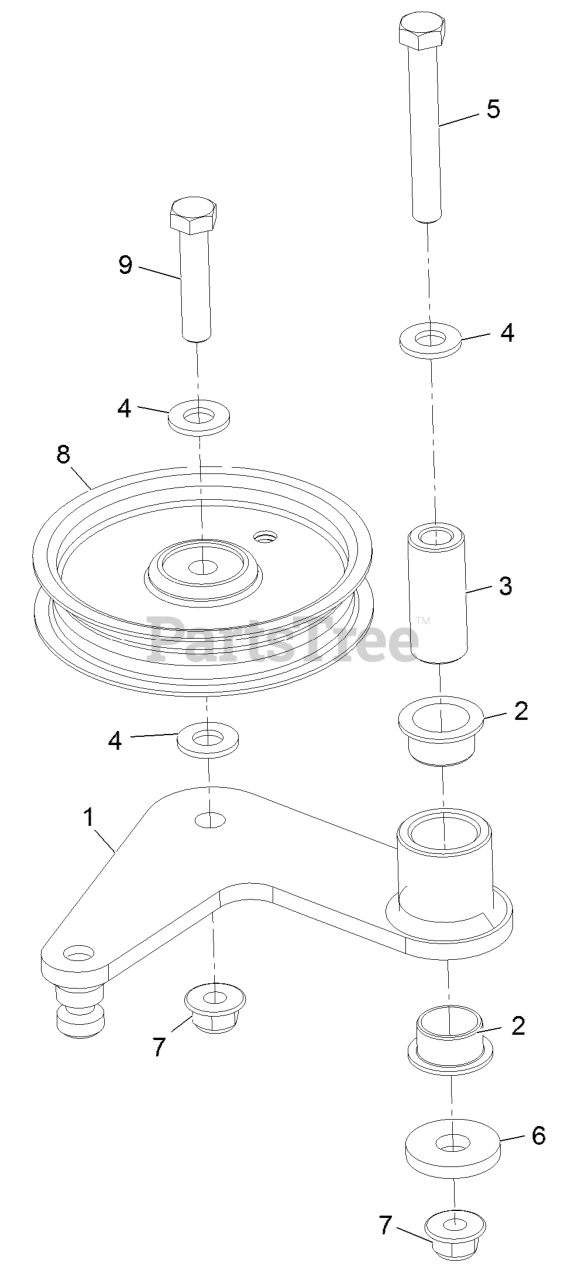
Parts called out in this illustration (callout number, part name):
1	Idler Arm ASM
2	Bushing-Flanged
3	Spacer, Pivot
4	Washer-3/8 Sae
5	Screw-HH 3/8-16 X 2 3/4
7	Nut-Nyloc 3/8-16 Flg
8	Pulley-Idler
9	Screw-HH 3/8-16 X 1 3/4
